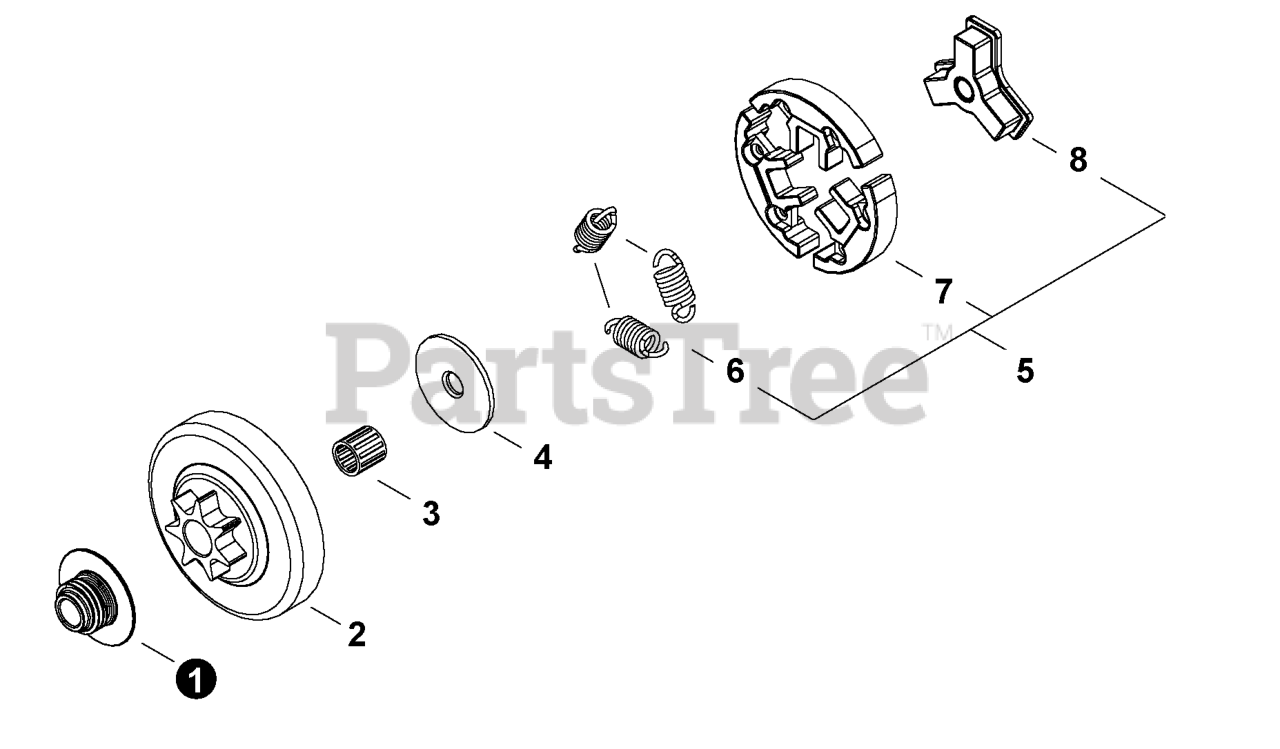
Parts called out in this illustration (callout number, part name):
1	GEAR, WORM
2	DRUM, CLUTCH
3	BEARING, NEEDLE 10
4	PLATE, CLUTCH
5	CLUTCH ASSY
6	SPRING, TENSION
7	CLUTCH SHOE SET (3PCS)
8	HUB, CLUTCH
